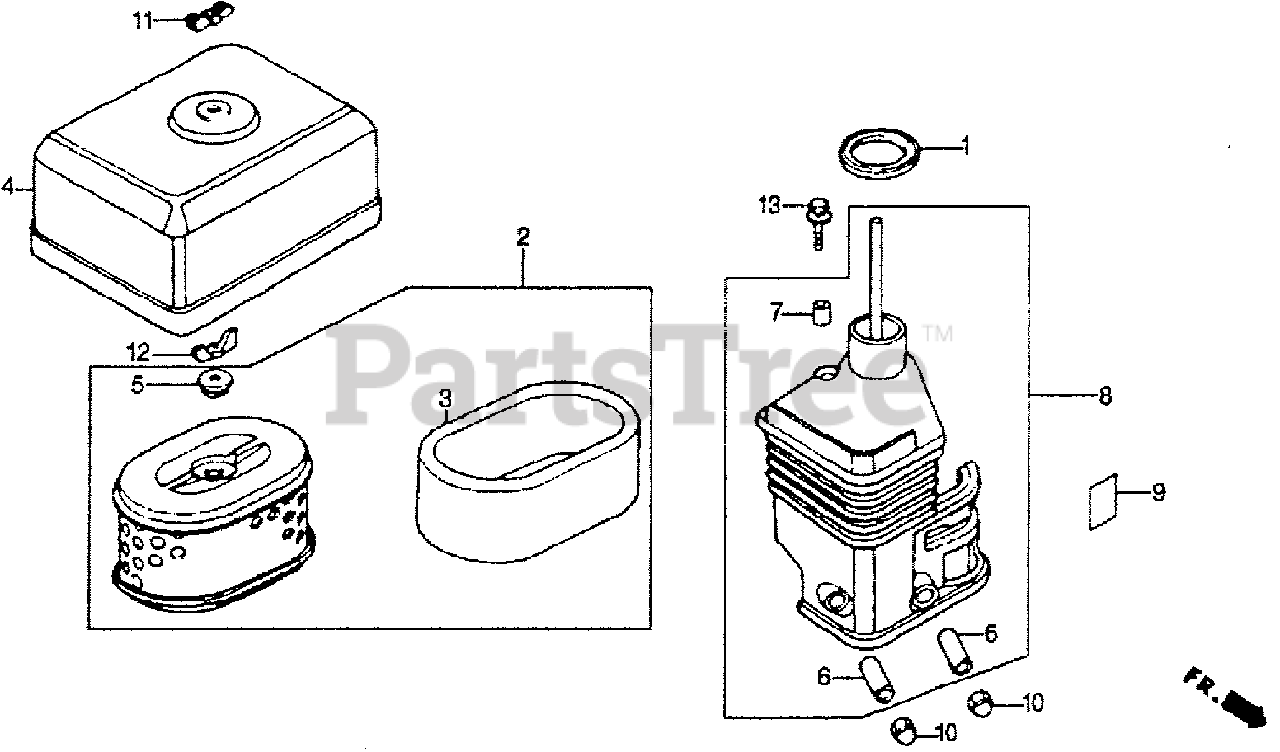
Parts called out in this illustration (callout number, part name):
1	GASKET, ELBOW
2	ELEMENT, AIR CLEANER (DUAL)
3	FILTER (OUTER)
4	COVER, AIR CLEANER (DUAL)
5	GROMMET, AIR CLEANER
6	COLLAR, AIR CLEANER
7	COLLAR B, AIR CLEANER
8	ELBOW, AIR CLEANER
9	MARK, CHOKE
10	NUT, CAP (6MM)
11	WINGNUT, AIR CLEANER COVER
12	WINGNUT, TOOL BOX SETTING
13	BOLT-WASHER (6X20)
